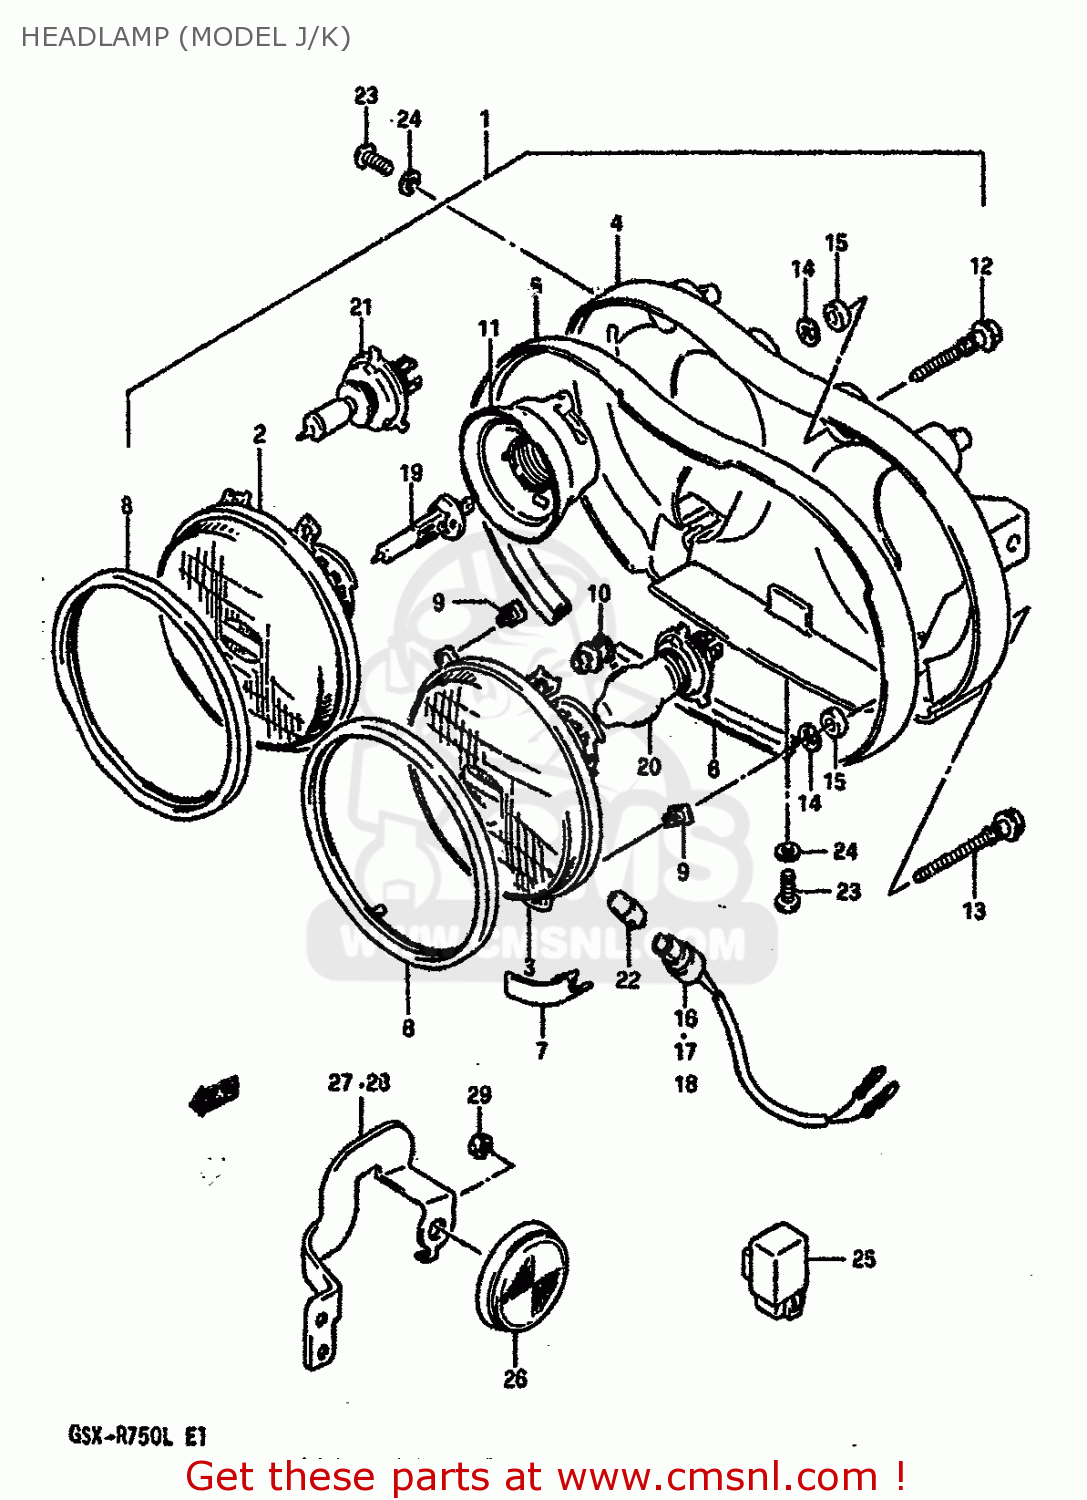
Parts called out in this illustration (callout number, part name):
1	HEADLAMP ASSY
2	UNIT,HEADLAMP RH
3	UNIT,HEADLAMP LH
4	HOUSING,HEAD LAMP
5	GASKET,HEADLAMP (NAS)
6	GASKET,HEADLAMP (NAS)
7	CUSHION
8	RING, RETAINING
9	NUT,HEADLAMP ADJUSTER
10	SCREW,SPHERICAL
11	COVER,SOCKET
12	SCREW,HEADLAMP ADJUST
13	SCREW,ADJUSTER
14	WASHER
15	BUSHING
16	SOCKET
17	SOCKET & CORD
18	SOCKET & CORD
19	BULB(12V55W/H1/P14.5S/OSRA,PHI
20	BULB (12V, 60/55W, H4)
21	BULB(12V60/55W,H4)
22	BULB(12V4W)
23	SCREW
24	WASHER,LOCK
25	RELAY ASSY,HEADLAMP
26	REFLECTOR,REFLEX FR
27	BRACKET,REFLECTOR
28	BRACKET
29	NUT
